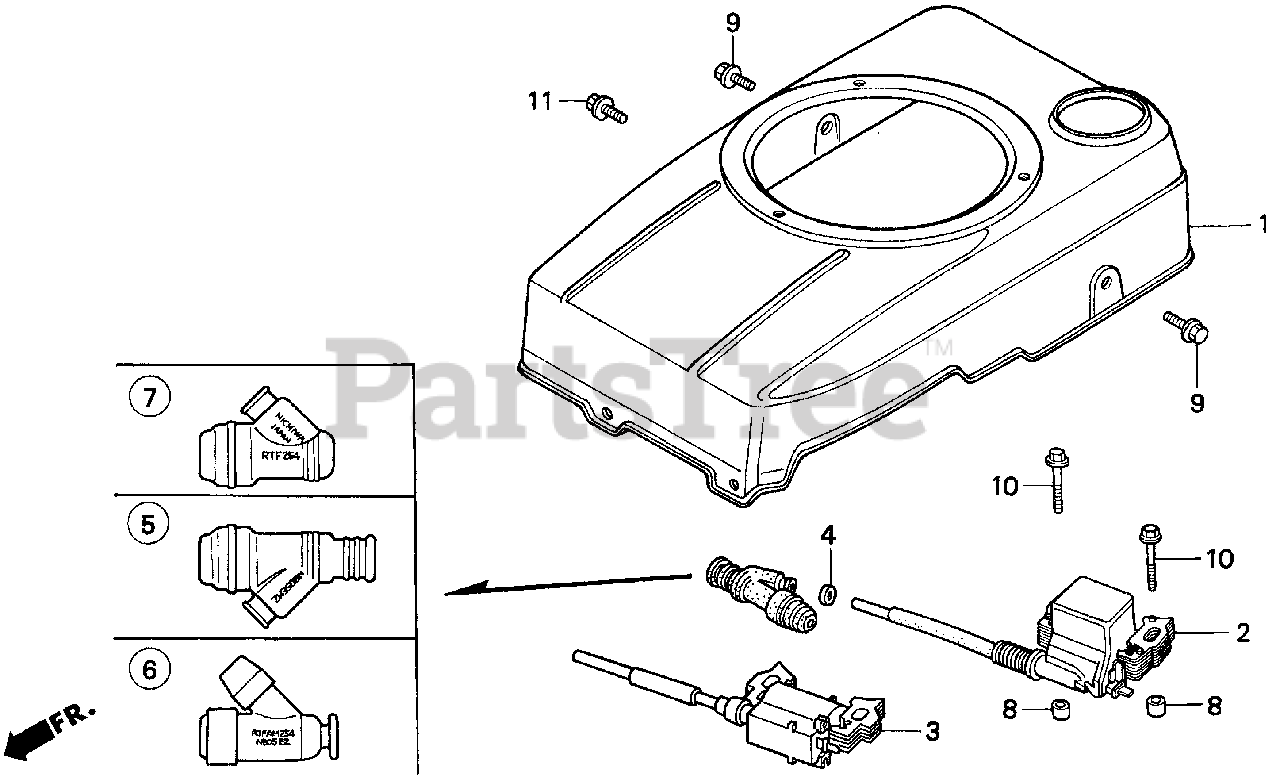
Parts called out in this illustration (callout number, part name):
1	COVER, FAN *R8* (BRIGHT RED)
1	COVER, FAN *R280* (POWER RED)
3	COIL ASSY., IGNITION
4	GROMMET, IGNITION WIRE
6	CAP ASSY., NOISE SUPPRESSOR
8	COLLAR, ROTO-STOP
9	BOLT, FLANGE (6X12) (CT200)
10	BOLT, FLANGE (6X35)
11	BOLT, FLANGE (6X10)
